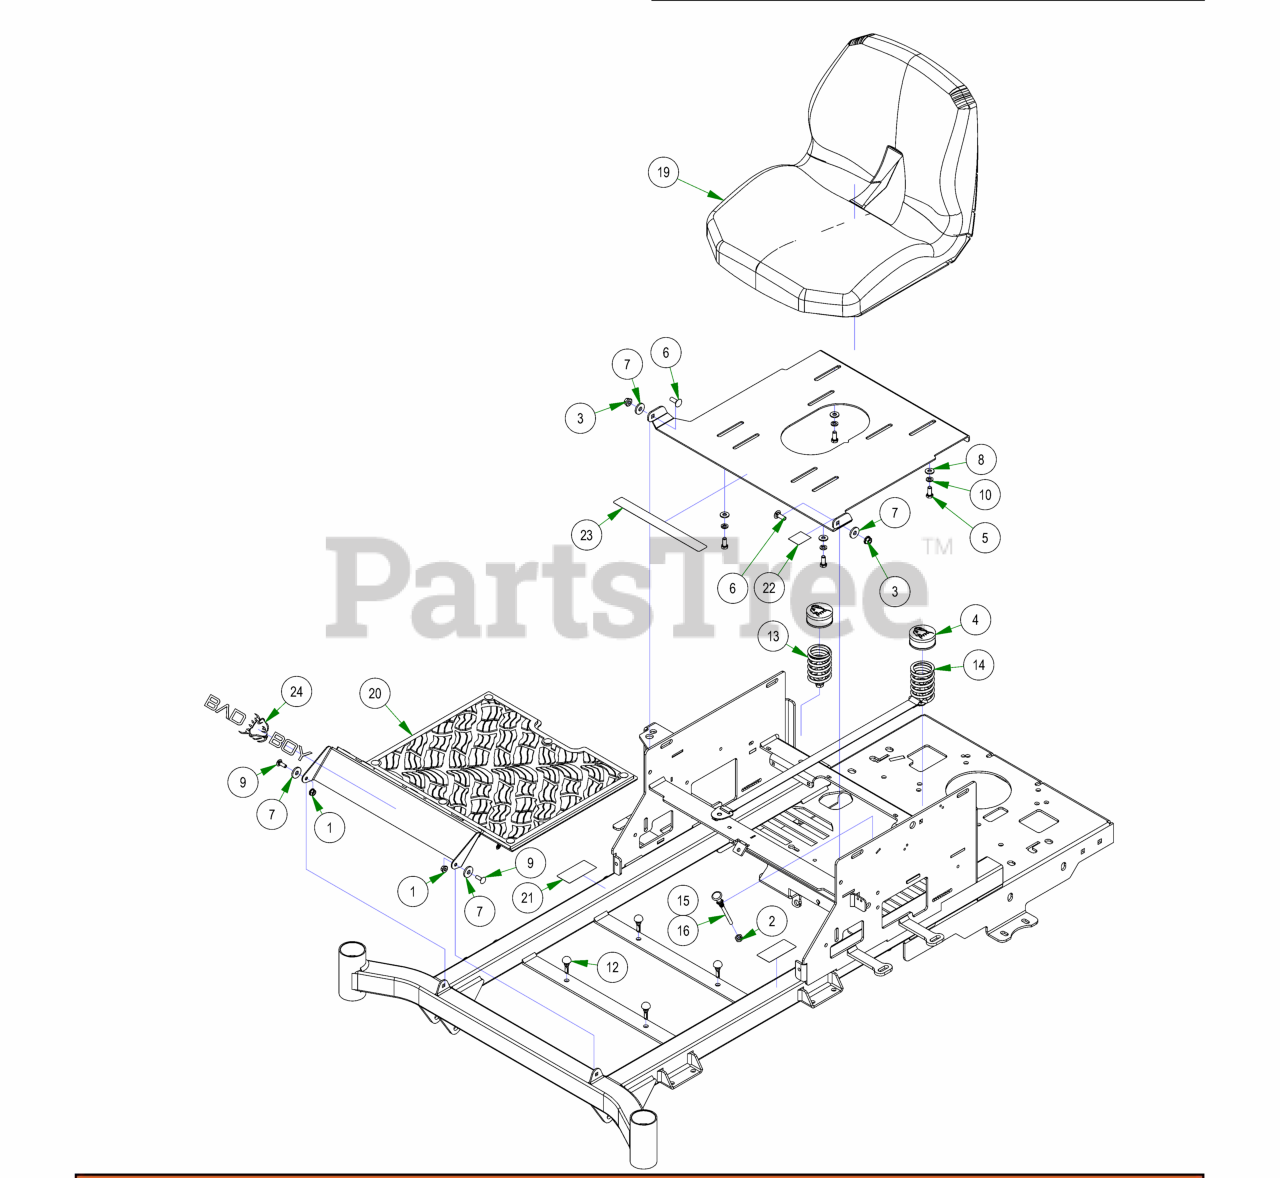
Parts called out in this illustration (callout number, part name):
1	1/4-20 NYL INSERT FLANGE LOCKNUT ZINC
2	3/8-24 HEX NUT ZINC YELLOW
3	5/16-18 NYLON INSERT FLANGE LOCKNUT ZINC
4	Spring Cap Cover
5	5/16-18 X 3/4 HEX CAP SCREW (GR.5) ZINC
6	5/16-18 X 7/8 CARRIAGE BOLT ZINC
7	.360 ID X .983 OD X .120 THICK FLAT WASHER NYLON
8	1/4 USS FLAT WASHER (3/4 OD) ZINC
9	1/4-20 X 3/4 CARRIAGE BOLT (GR.5) ZINC
10	5/16 SPLIT LOCKWASHER ZINC
11	2022 Avenger Seat Plate
12	2023 Floor Board Rubber Bumper
13	Seat Spring Assembly
14	2022 Mav/HD seat spring assembly with strap
15	Choke 42" Only
17	2024 MZ 42-48 Frame
18	2024 MZ-Avenger 54-60 Frame
19	2022 Magnum Seat
20	2020 MZ AVEN Floorboard Assembly
21	2018 LH/RH Steering Control Decal Roll
22	2018 MZ/Magnum/ZT/MAV/Comp Out Brake Decal
23	Outlaw Warning Decal
24	Flying Bulldog Front Bumper Decal
